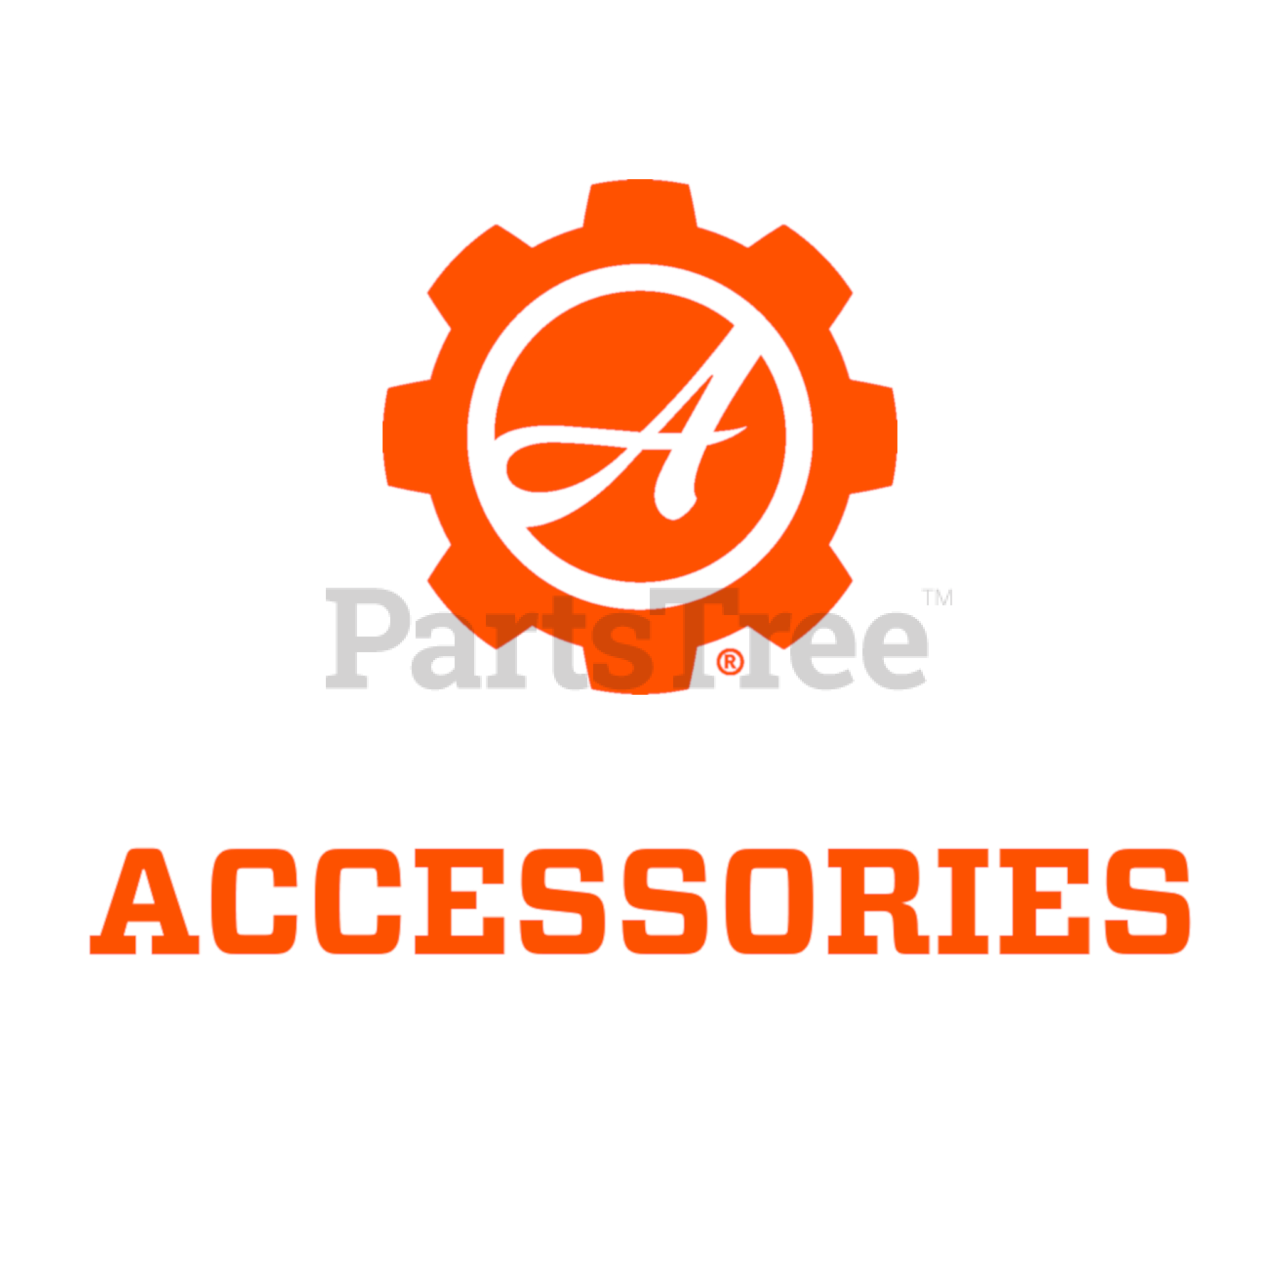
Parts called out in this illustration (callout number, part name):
1	E-START CORD W SLEEVE
2	FLOOR MAT, 30 X 36" ARIENS
3	KIT, SNOW CAB ENCLOSURE
4	SNOW CAB,GENERATION 2.0
5	KIT, FRONT WEIGHT-10 LBS
6	KIT, SKID SHOES ORANGE ARIENS
7	KIT, CLEAN OUT DEVICE
8	KIT, SNOW CLEAN-OUT W/ BRUSH
9	MAINT KIT, 2011-12 DELUX / PRO
10	SNO THRO COVER LARGE (PRO-DLX)
11	KIT,PRO SKID SHOES ORANGE
12	SLICER BAR KIT - ORANGE
13	KIT, SKID SHOES (2)
14	KIT, LED, DASH HEADLIGHT REPL
